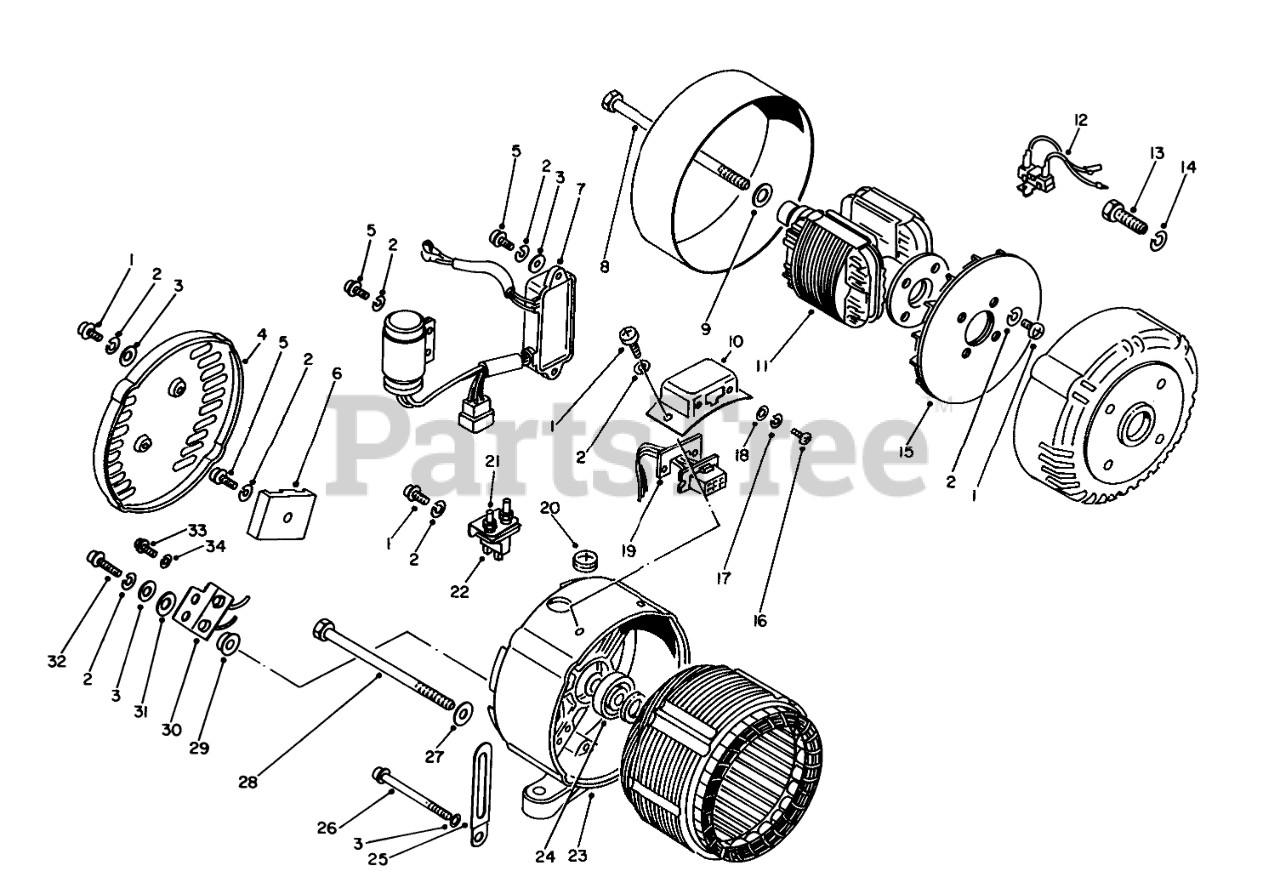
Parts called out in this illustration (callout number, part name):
1	SCREW
2	Washer
3	WASHER
4	Cover-Rear
5	Screw
6	Terminal
7	REGULATOR
8	Bolt (8 x 117)
9	Washer
10	COUPLER COVER
11	Rotor
12	Register
14	Lockwasher
16	SCREW
17	Lockwasher
18	Washer
19	Plate
20	GROMMET
21	Holder
22	BRUSH
23	Generator (120V)
24	Bearing
25	Clamp
26	Screw
27	Washer
28	Bolt (6 x 160)
29	Washer
30	DIODE
31	Brush
32	Screw
34	Lockwasher
